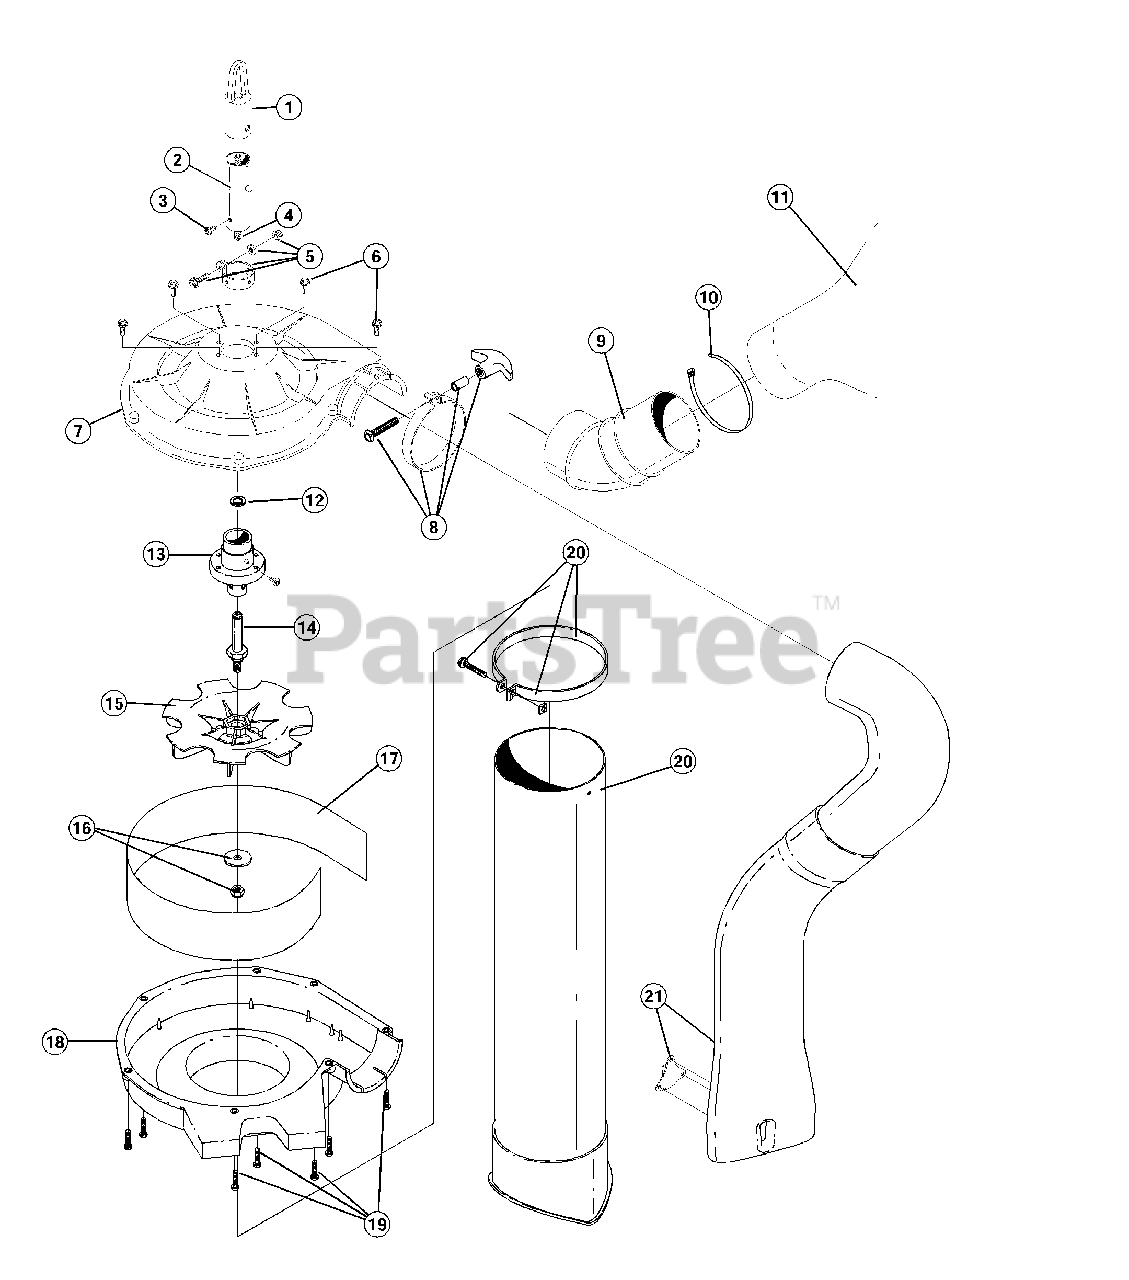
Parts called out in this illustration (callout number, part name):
1	Hanger
2	Boom Assembly
3	Anti-Rotation Screw
4	Drive Shaft Assembly
5	Lower Clamp Assembly (includes 3)
6	Mounting Screw
7	Upper Housing
8	Clamp Assembly
11	Vacuum Bag Assembly (includes items 9 and 10)
12	Palnut
13	Bushing Housing Assembly
14	Impeller Shaft
15	Impeller
16	Nut and Washer Assembly
18	Lower Housing
19	Mounting Screw
20	Vacuum Tube Assembly
21	Blower Tube Assembly
